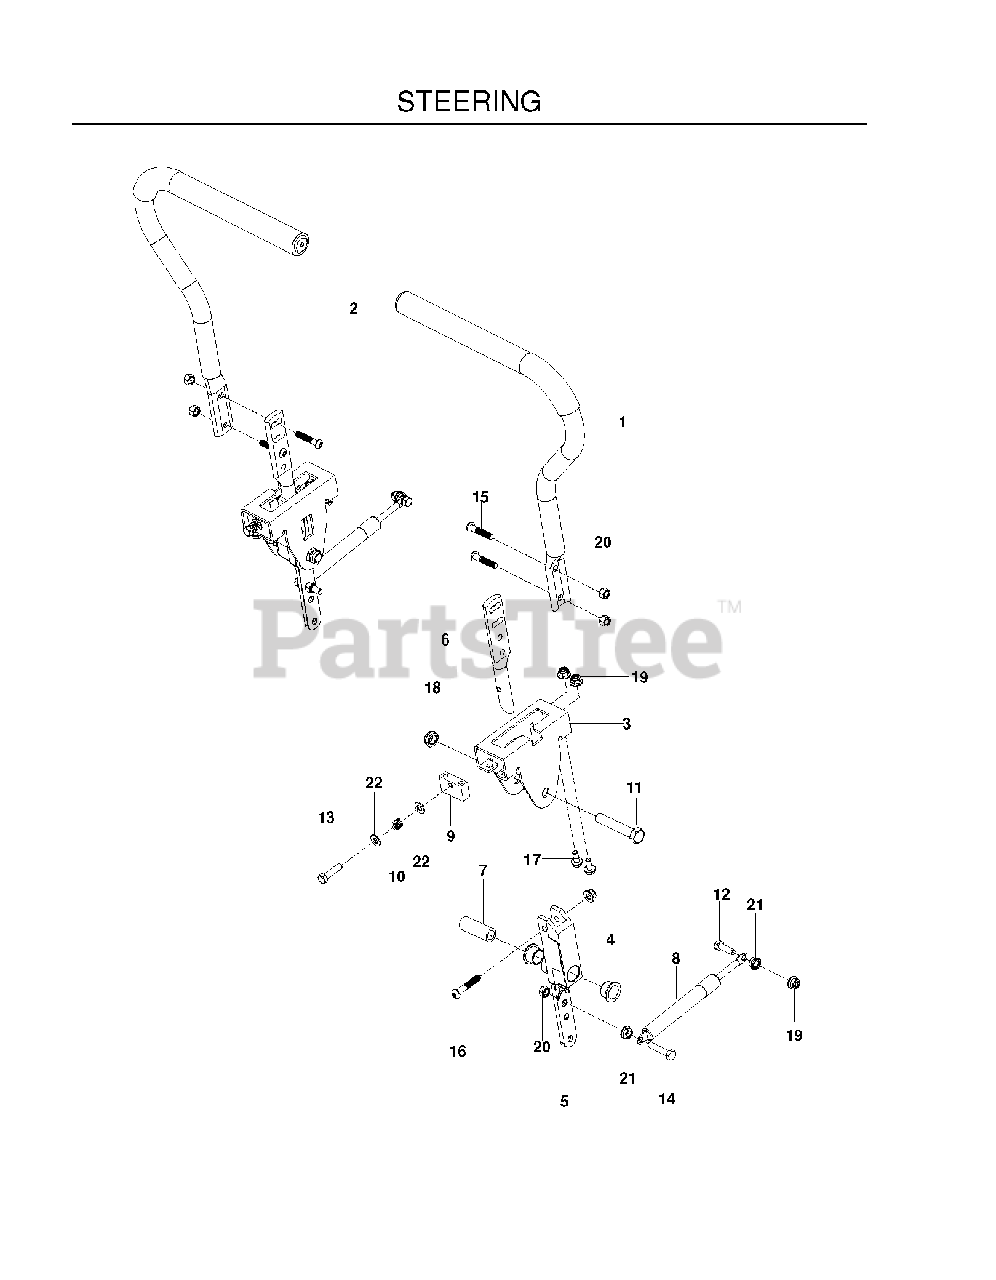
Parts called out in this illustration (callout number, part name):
1	LEVER.STEERING.ASM.(W/GRIP)
2	GRIP, DRIVE LEVER
3	BRACKET, CONTROL
4	BEARING, FLANGE
5	LEVER CONTROL PIVOT
6	LEVER.HANDLE MOUNT
7	SPACER, PIVOT CONTROL
8	DAMPENER
9	BLOCK.TRACKING
11	HCS 1/2C X 2 3/4
12	HCS 5/16C X 1
13	CAPSCREW 5/16 X 1/1/2 HEX HEAD
14	HCS 5/16C X 1 3/4
15	SCREW 5/16-18 X 1 BTN-HD
16	SCREW 5/16-18 X 1 3/4 BTN-HD
17	HHFS 5/16-18 X 3/4
18	NUT 1/2-13 HEX JM NYL
19	5/16-18 NYLOC FLANGE NUT
20	NUT 5/16 NYLOC
21	NUT 5/16C WHIZ
22	FLAT WASHER 5/16 SAE
